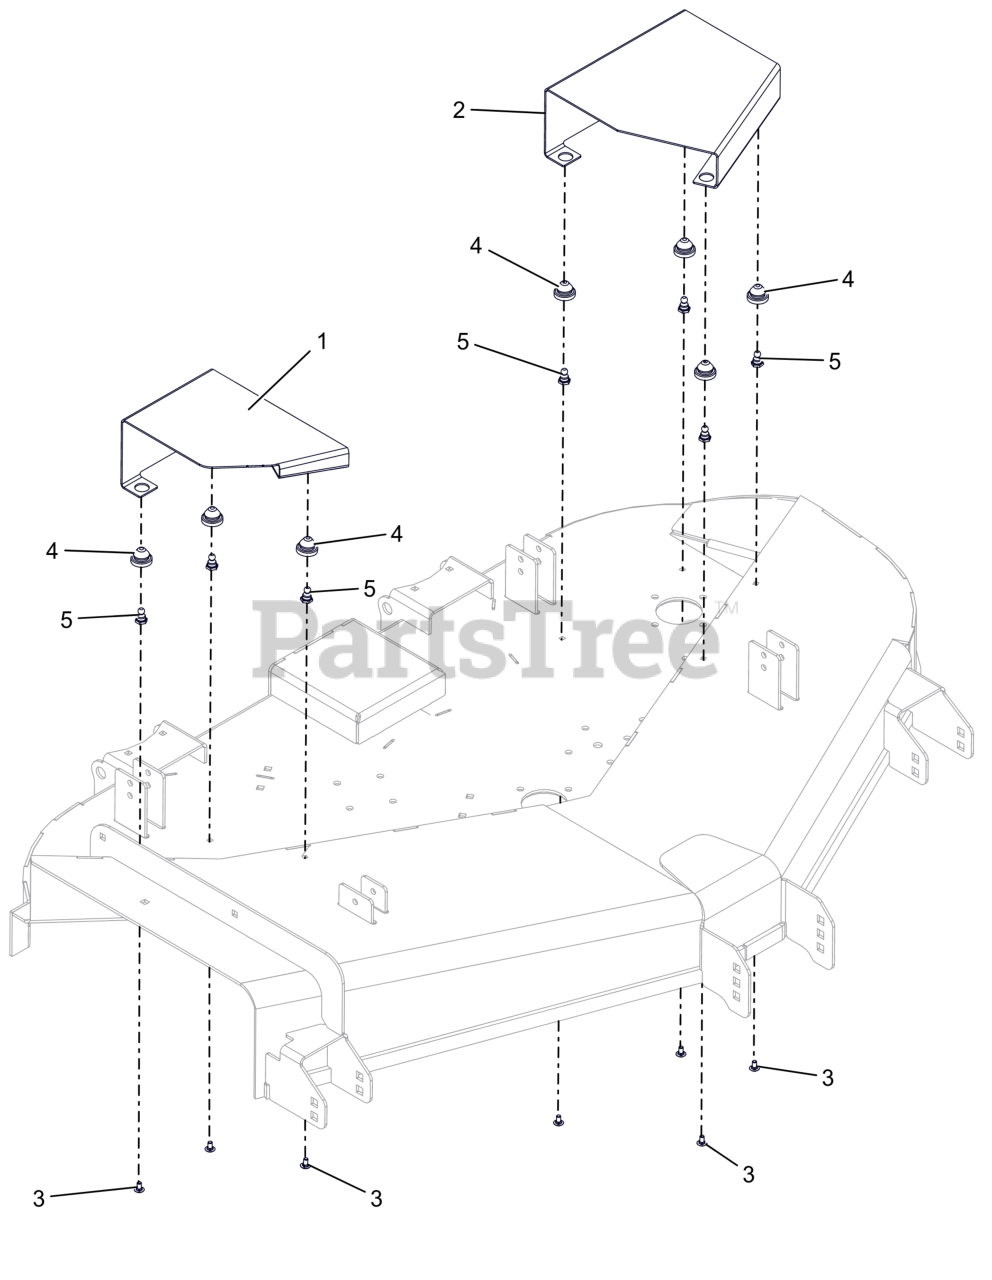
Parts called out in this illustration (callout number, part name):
1	COVER, RH BELT - TUNNEL DECK (RED)
2	COVER, LH BELT - TUNNEL DECK (RED)
3	BLT, RHSSN.25-20X.500 G5 ZCC
4	COUPLING, RUBBER PUSH-IN
5	STUD, BALL FEMALE .250-20 THREAD
